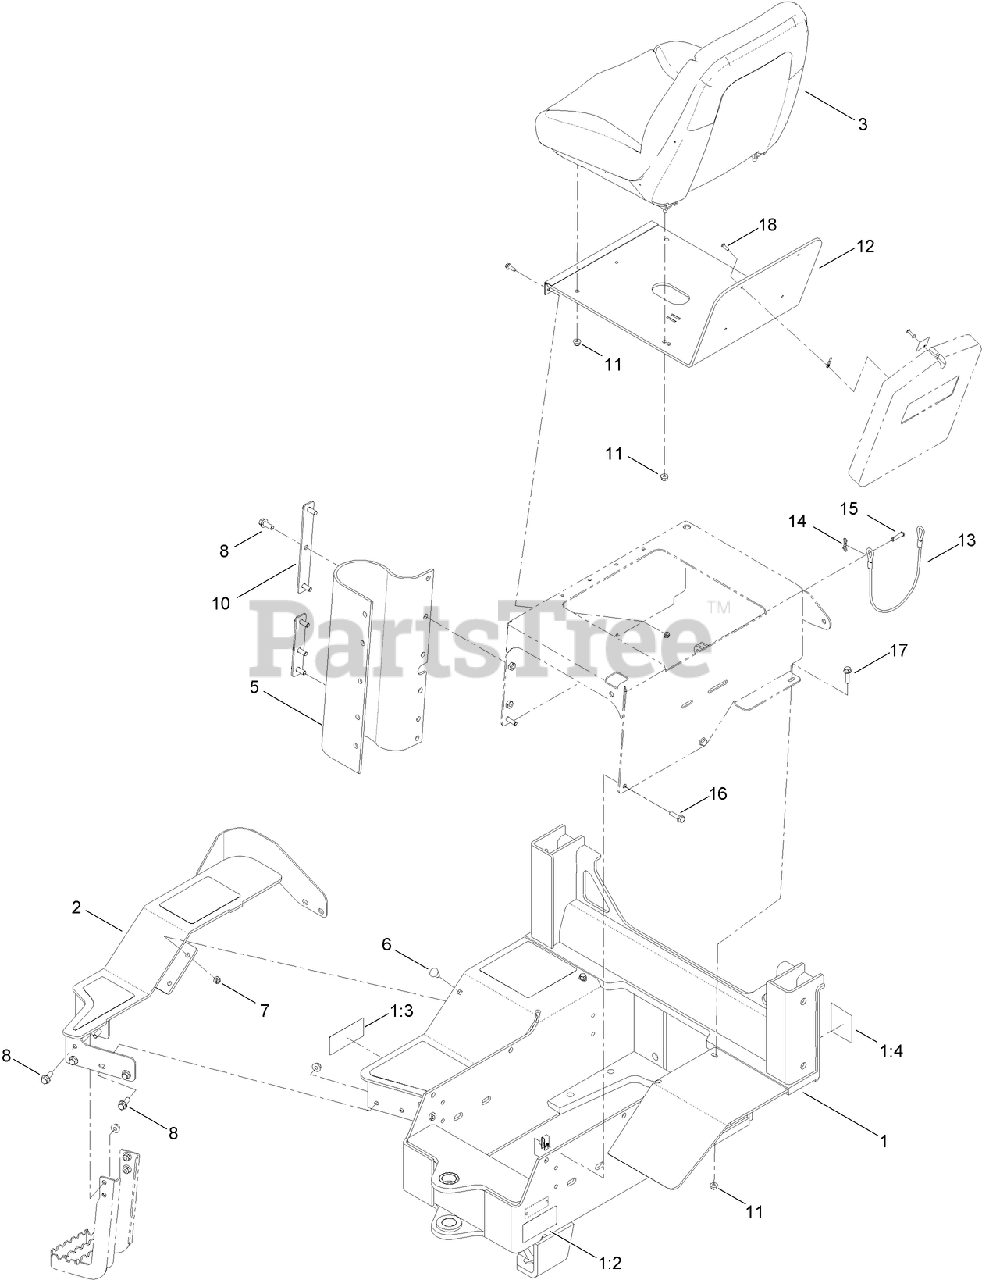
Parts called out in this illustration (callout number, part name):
1	REAR FRAME ASM
1:2	DECAL-DANGER, ARTICULATED JOINT
1:3	DECAL-WARNING, STEP EXTENSION
1:4	DECAL-LIFT HERE
2	PLATFORM-EXTENSION
3	SEAT ASM
5	SHIELD-RUBBER
6	SCREW-CARR
7	NUT-LOCK, NI
8	SCREW-HHF
11	NUT-HF, NI
12	PLATE-SEAT
13	CABLE-SEAT
14	PIN-COTTER, LOCKING
15	PIN-CLEVIS
16	SCREW-HHF
17	SCREW-HHF
18	RIVET-POP
